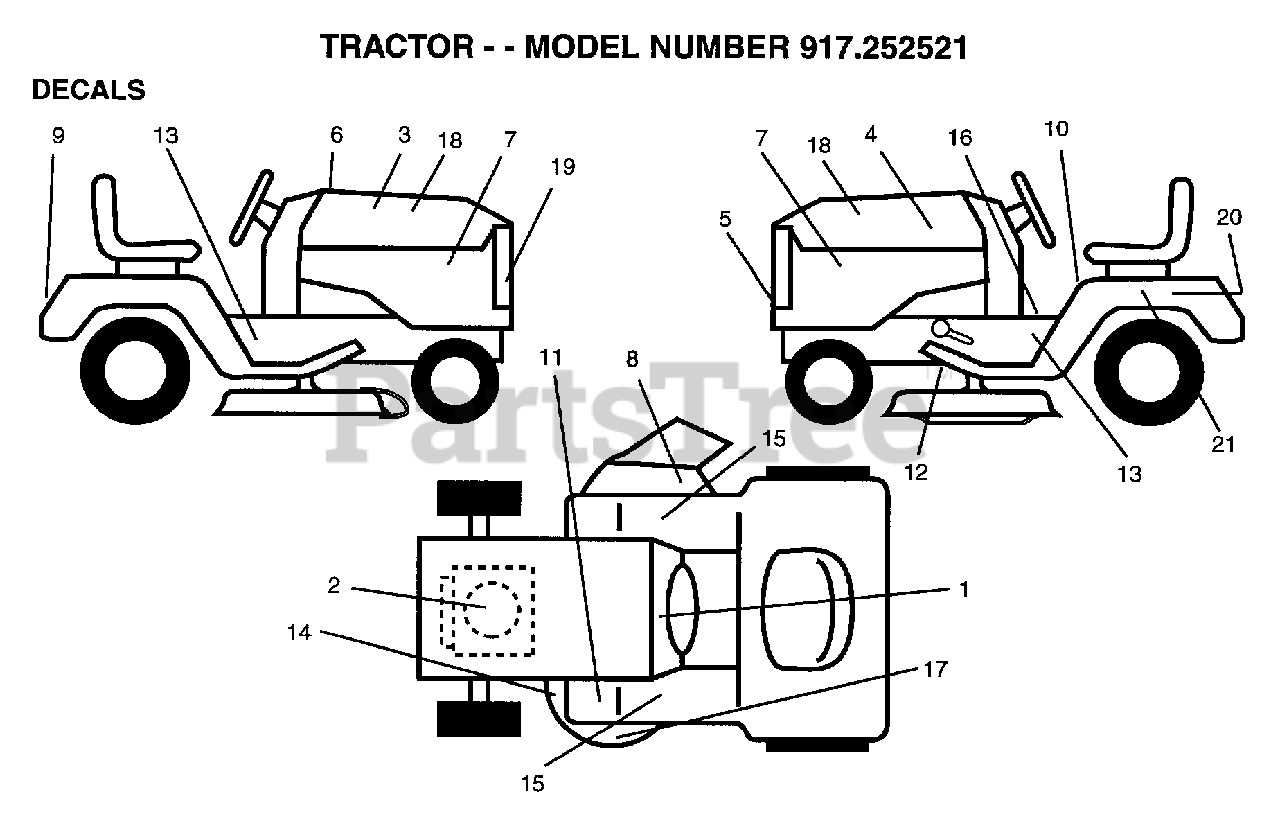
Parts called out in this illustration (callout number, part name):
1	DECAL.DASH.INST.
2	DECAL,B&S 15HP IC/GOLD OHV
3	DECAL.HD.RH.CRAFT
4	DECAL.HD.LH.CRAFT
5	GRILL DECAL
6	DECAL
7	DECAL SIDE PAN IC
8	MOWER DECAL
12	DECAL.BELT-V.SCHM
13	CHASSIS DECAL
14	DECAL
16	DECAL BRAK PARK
17	DECAL MWR QC SYS
18	DECAL INS HOOD
19	DECAL LIGHTBOX
20	DECAL.BTRY.SRS.EN
21	DECAL.BTRY.CRAFT.
